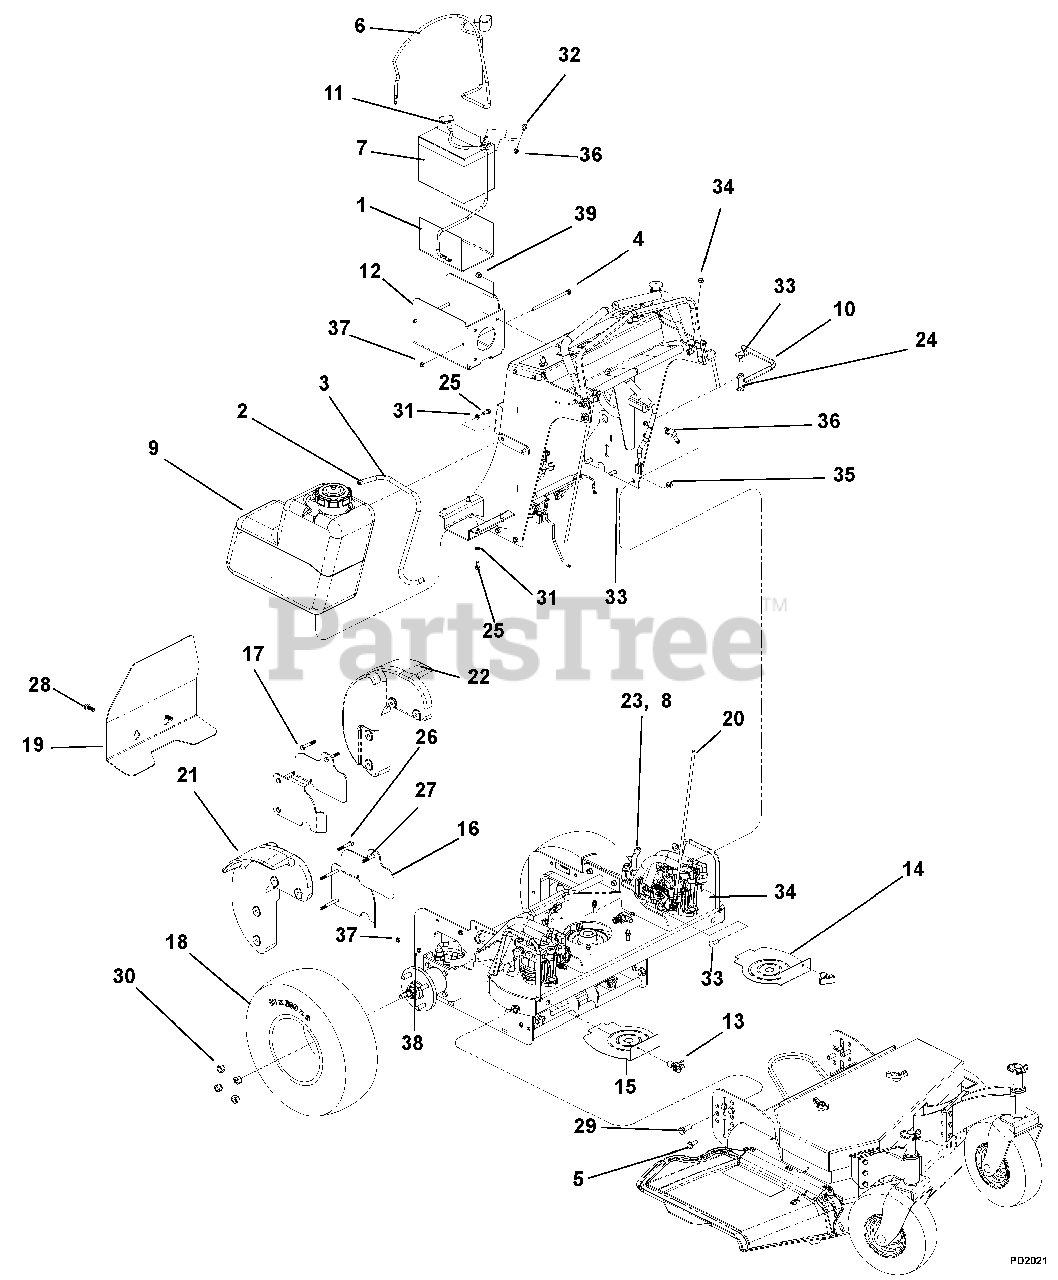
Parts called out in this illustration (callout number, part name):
1	Pad, Battery Insulator
2	Clamp, Hose (Red) #
3	Hose, 1/4" Id Low Perm Fuel 50
4	Cap Screw, 5/16" x 6"
5	Bolt, 1/2 x 1.06 x 3/8-16 Sld 5 Y
6	Cable, Battery Starter -48"
7	Battery, 12V-U1-CCA 270 min
8	Pin, Clevis Spg 3/8" Yoke Spec Y
9	Tank, Fuel
10	Weldment, Reservior Guard
11	Cable, Battery -25" Ground
12	Console Battery Bracket
13	Latch, Beckson
14	Shield, LH Pump
15	Shield, RH Pump
16	Shield, RH Motor
17	Shield, LH Motor
18	Assy, Tire/Whl 18/6.5x8 Slvr
19	Shield, Engine
20	Rod, Control 5/16 x 22.75 Y
21	RH Cast Weight Machined
22	LH Cast Weight Machined
23	Clevis, .38-24 Adjustment
24	Bolt, Hex .25-20 x .75 Grade 5
25	Bolt, Hex .25-20 x .75 Grade 5
26	Bolt, Hex .31-18 x .75 Grade 5
27	Bolt, 5/16-18 x 3.00 Hex 5 Y
28	Bolt, 3/8-16 x 1.00 Fgh 8 Y
29	Bolt-Hex .50-13 x 1.25 Grade 5
30	Nut, 1/2-20 Lug C
31	Washer, .313 Med Sprg Lock Y
32	Bolt, 1/4-20 x .625 Wsh Y
33	Bolt, Round Head Square Neck .38-16 x 1.00 Grade 5
34	Nut, Hex .312-24
35	Nut, Flange .375-16
36	Nut, Locking-Flange .250-20
37	Nut, Locking-Nylon .312-18
38	Nut, Spin Lock-Flange .50-13
39	Nut, Locking-Nylon .38-16
